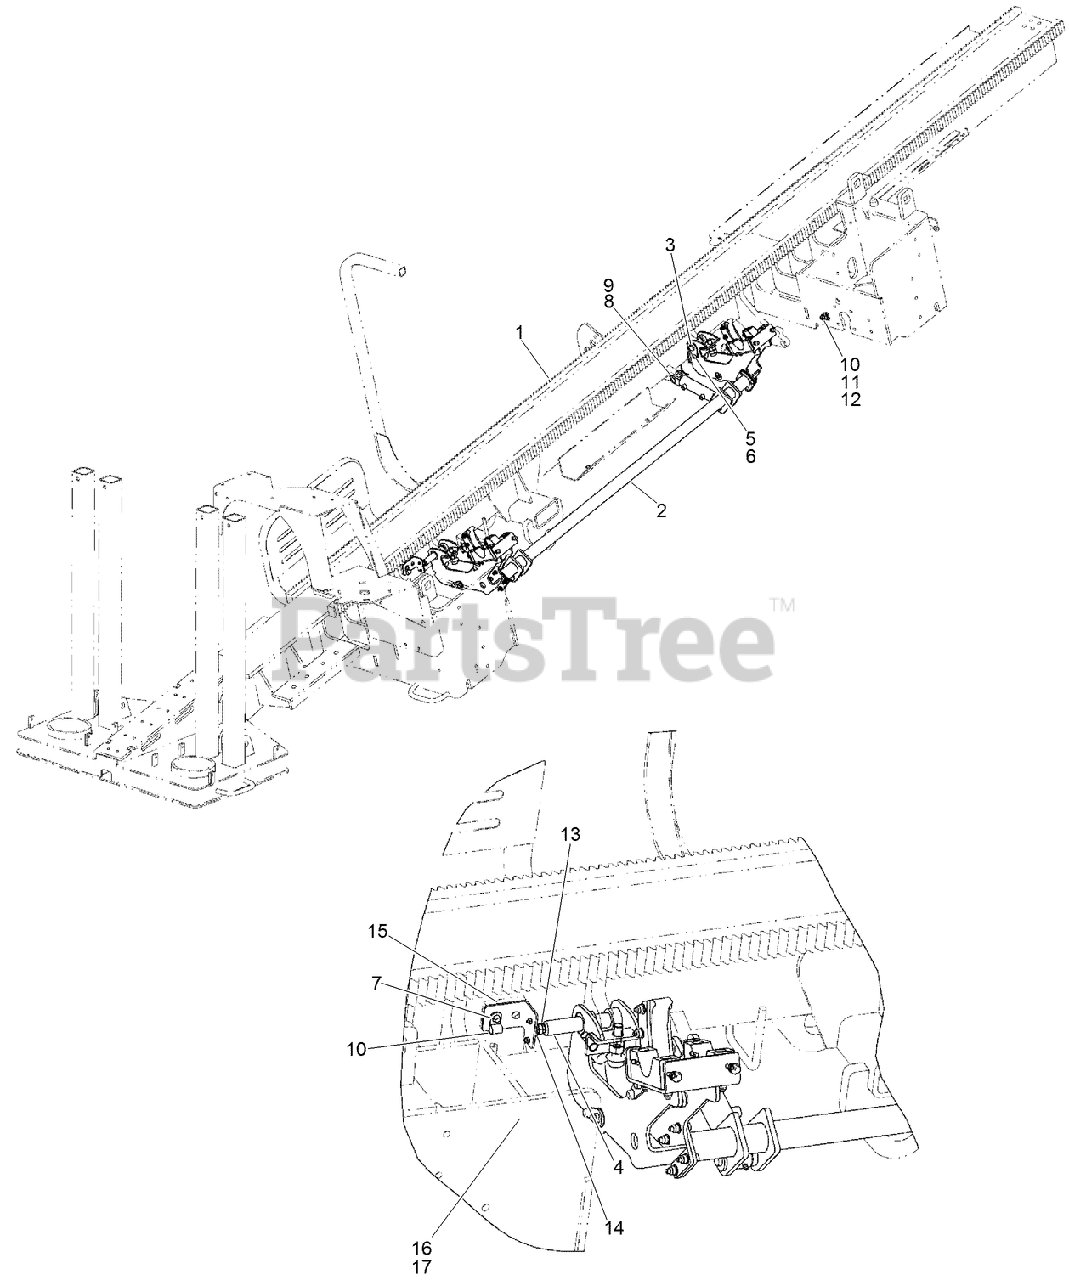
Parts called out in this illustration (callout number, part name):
1	WELDMENT - Thrust Frame
2	ASSEMBLY - Rod Loader
3	PIN-PIVOT, CAM
4	PIN-PIVOT
5	SCREW-HH
6	NUT-TORQUE, PREVAILING
7	SCREW, METRIC FLANGE w/BODY - M6 x 12
8	PIN-CLEVIS
9	PIN-cotter, 5/32 x 1-3/4 inch
10	CLAMP - Insul, 12.7mm 3/8 in Bolt ZND
11	NUT-FLANGE, NYLOCK
12	SCREW-HHF
13	JAM NUT - M10 - 1.0
14	SENSOR - Rotary
15	PLATE - Mounting
17	NUT-#8-32 KEPS
